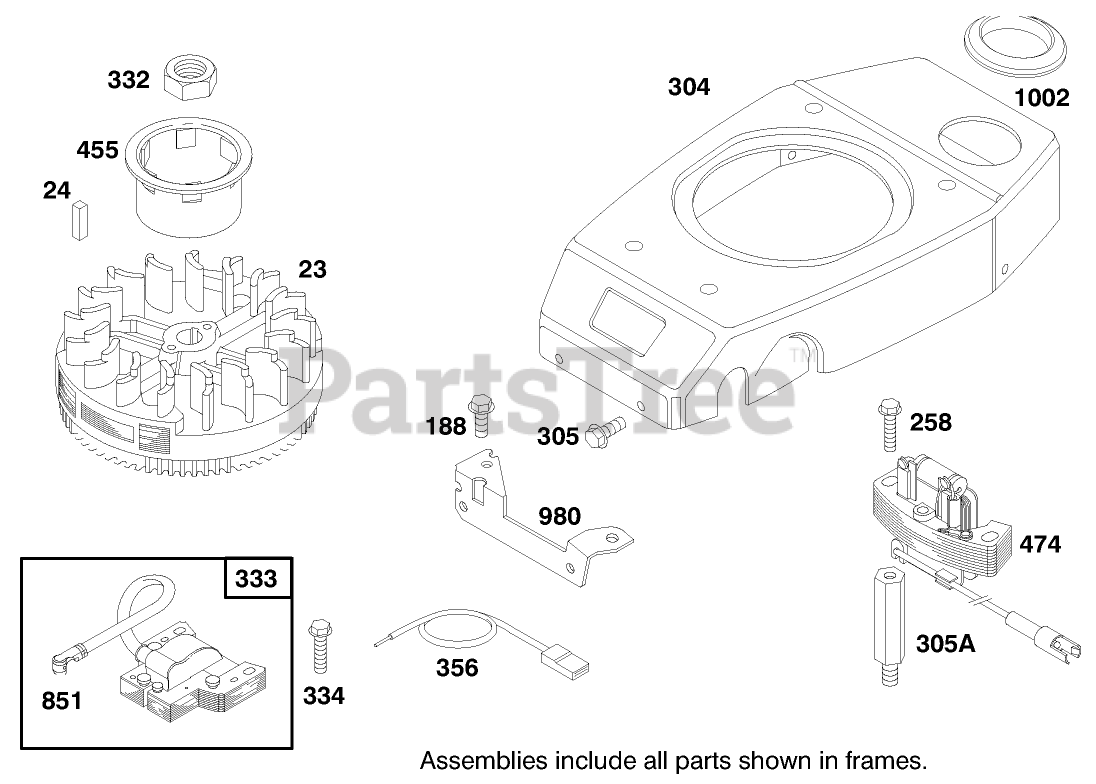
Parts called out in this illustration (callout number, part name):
23	FLYWHEEL - MAGNETO
24	KEY - FLYWHEEL
188	SCREW - SEM
305	SCREW - HEX HEAD
332	NUT - HEXAGON
356	WIRE - GROUND
980	BRACKET-BLOWER HSG
